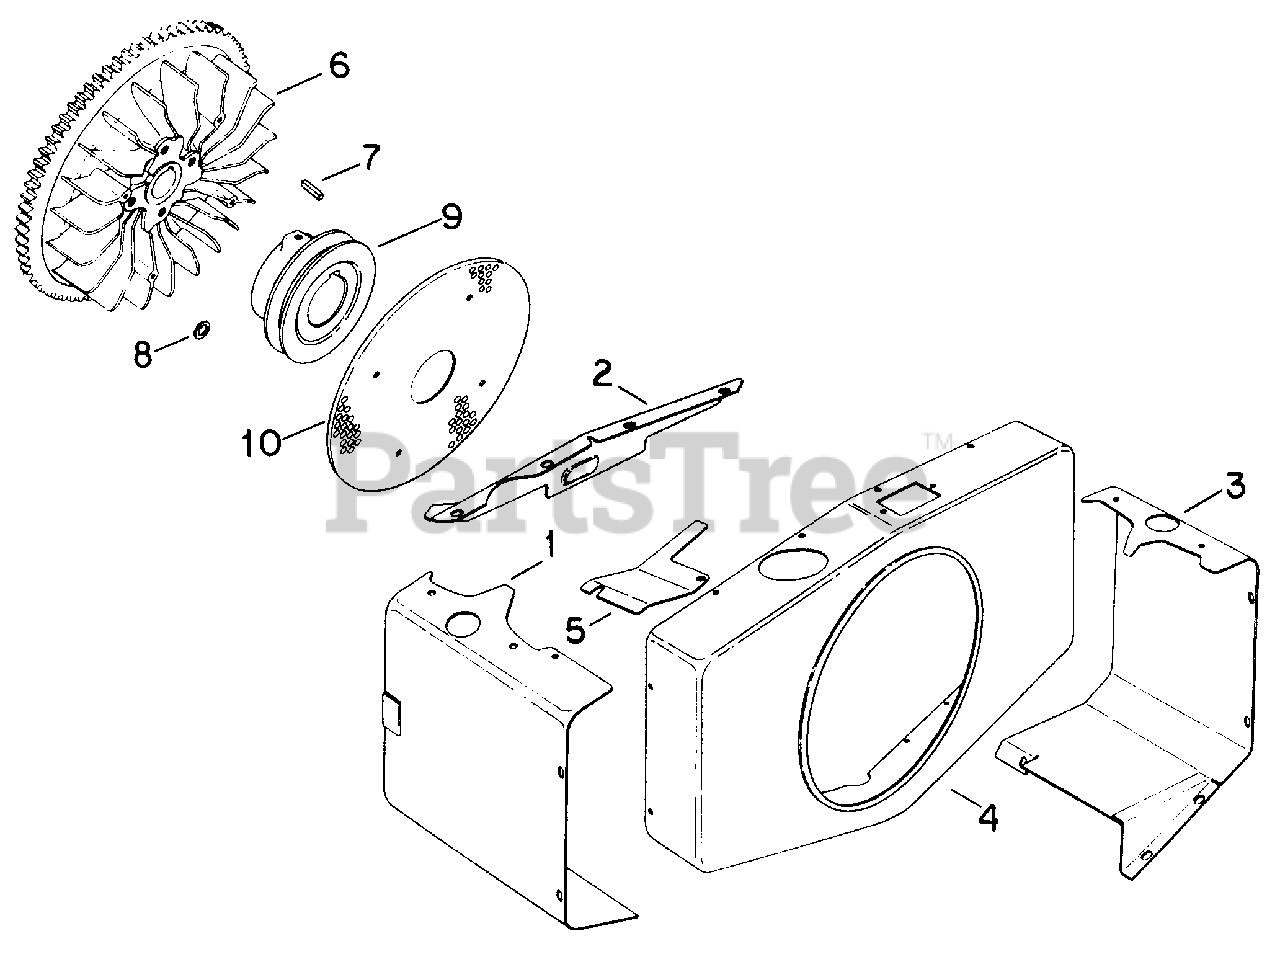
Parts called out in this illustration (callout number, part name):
1	Shroud, Cylinder Head
2	Support, Upper Housing
3	Shroud, Cylinder Head
4	Housing, Blower
5	Shroud, Cylinder Top
6	Flywheel Assy
8	Washer, Flywheel
10	Kit, Grass Screen
